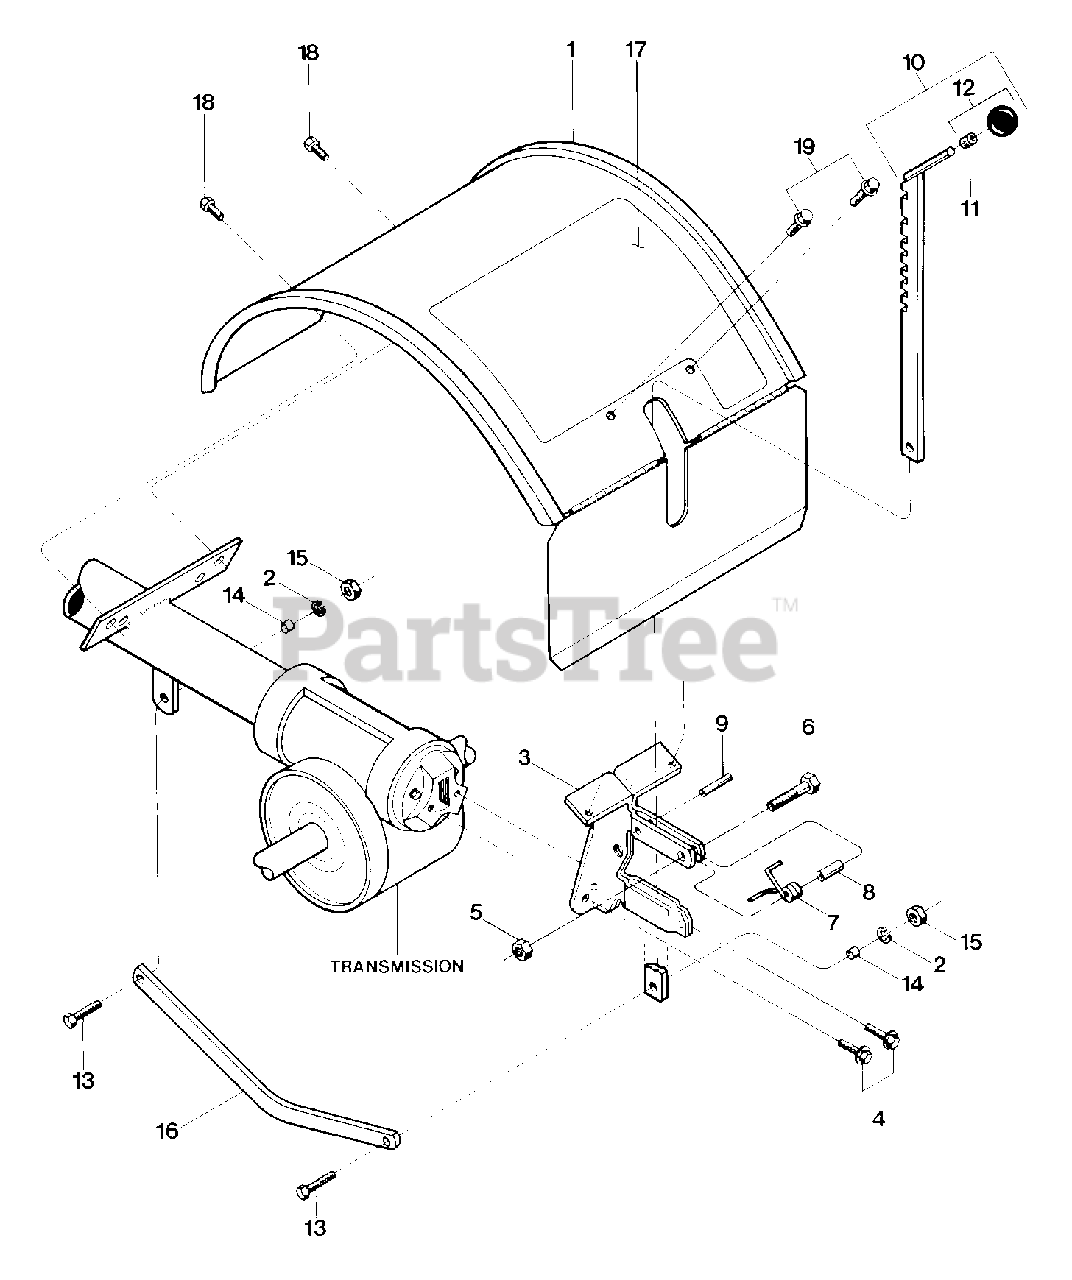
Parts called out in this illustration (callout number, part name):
1	Tine Hood
2	Lockwasher, 3/8
3	Bracket-hood & depth regulator
4	Hex Flange Screw, 5/16-18 x 5/8
5	Hex Locknut, 1/4-20
6	Hex Hd. Screw, 1/4-20 x 1
7	Spring
9	Roll Pin (spiral), 1/4 x 1
10	Depth Adjustment Bar Assembly
11	Retaining Ring (tolerance ring)
12	Knob, Depth Regulator
13	Hex Hd. Screw, 3/8-16 x 1-1/4
14	Bushing, Drag Bar
15	Hex Nut, 3/8-16
16	Drag Bar
17	Decal, operating instructions
18	Hex Hd. Screw, self-tapping, 5/16-18 x 1/2
19	Hex Flange Screw, self-tapping, 1/4-20 x 1/2
